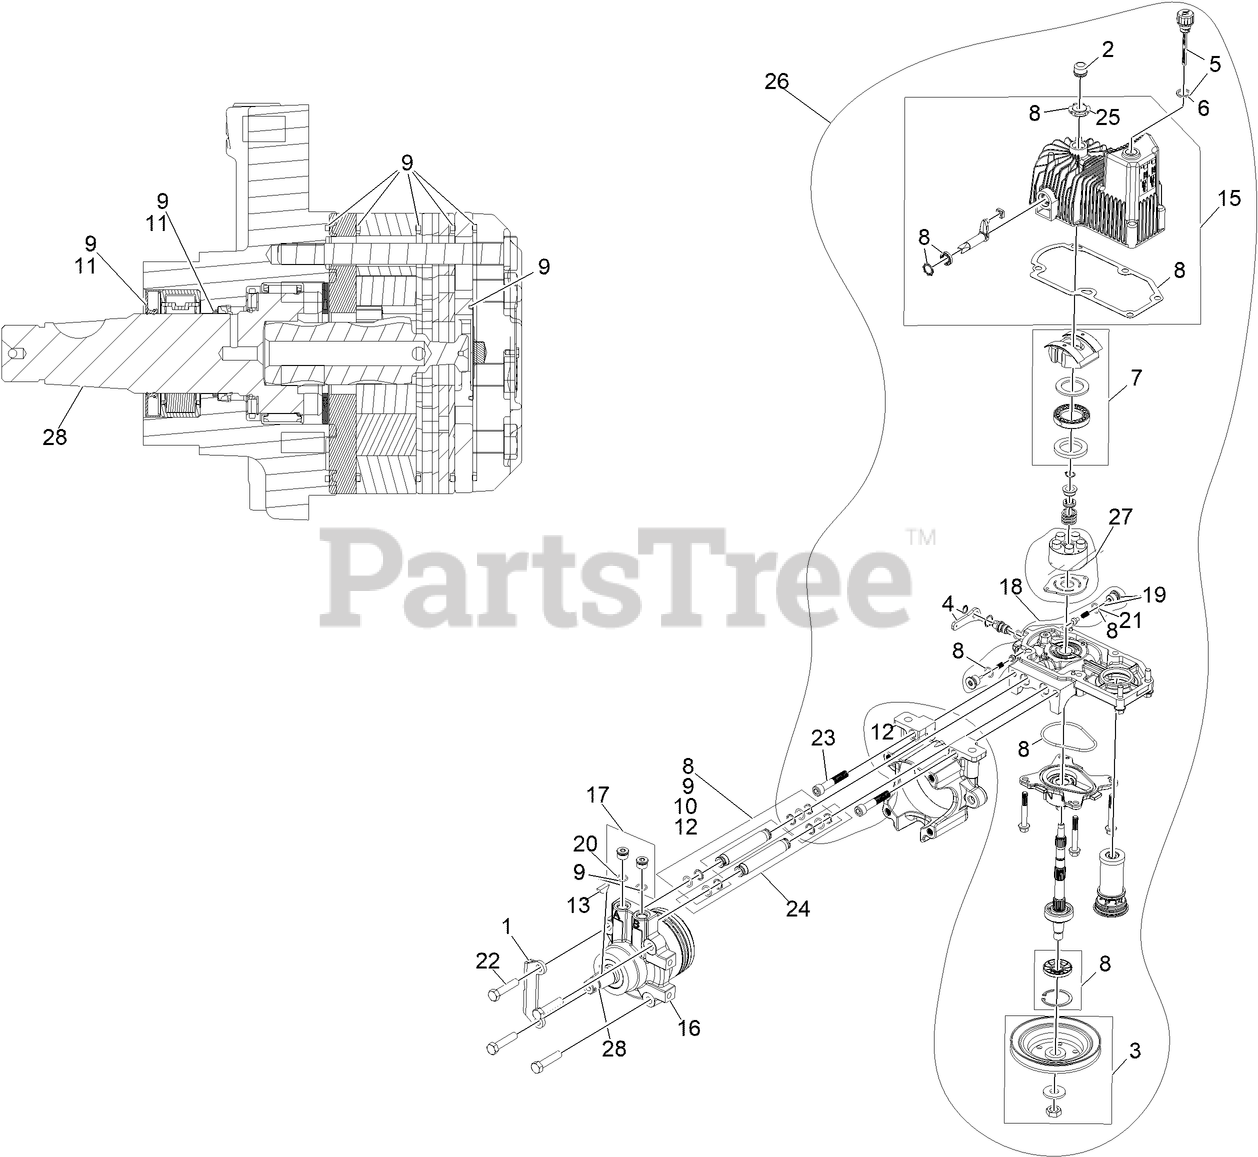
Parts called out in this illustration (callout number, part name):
1	Plate, Horse Shoe Mount
2	COVER-SHAFT, HYDRO
3	PULLEY KIT
4	HANDLE-BYPASS VALVE, HYDRO
5	DIPSTICK-HYDRO W/GASKET
6	GASKET-DIPSTICK, HYDRO
7	SWASH BLOCK KIT
8	Kit, Pump Seal
9	MOTOR SEAL KIT
10	TUBE SEAL KIT
11	OUTPUT SHAFT SEAL KIT
12	NOSE CUP-UHT
13	KEY-WOODRUFF
15	Kit, Housing-Hydro RH
16	MOTOR-HYDRAULIC RH 240CC
17	MAGNETIC PLUGS SERVICE KIT
18	ASM, CHECK VALVE
19	PLUG-CHECK (W/O-RING)
21	O-RING-CHECK VALVE
22	SCREW HH
23	SCREW-HSH
24	HYDRAULIC TUBE KIT
25	SEAL-FAN DRIVE
26	KIT, PUMP SECTION 12CC RH NO FAN
27	Kit - 12Cc Port Plate,Rotate Grp
28	OUTPUT SHAFT- TL UHT MOTOR
